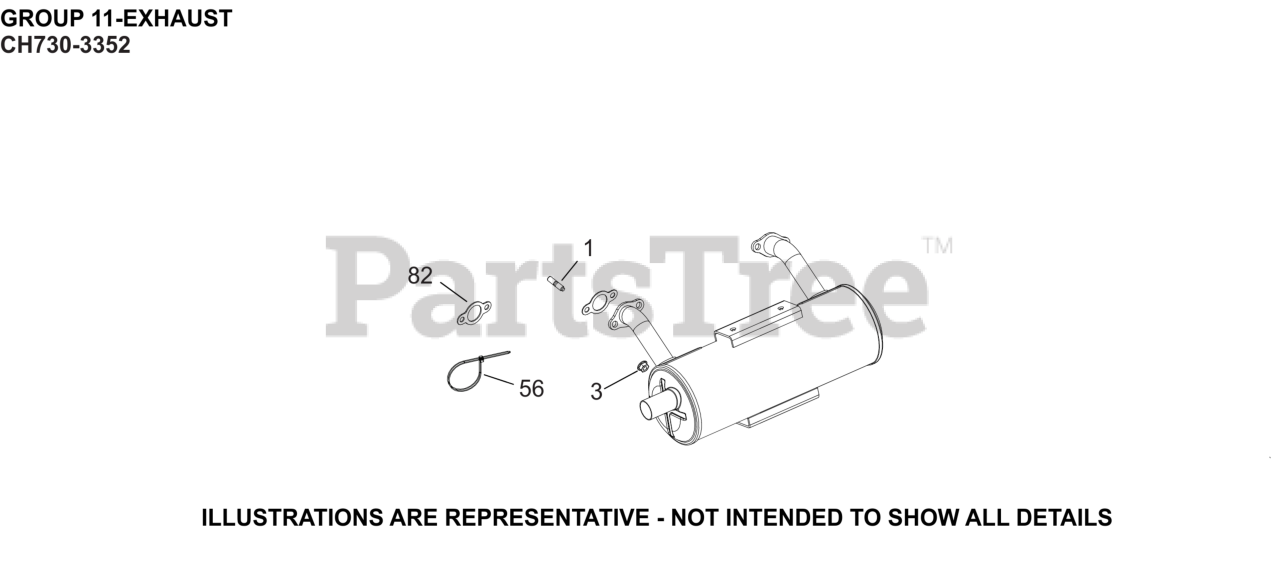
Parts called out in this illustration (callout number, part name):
1	STUD, METRIC EXHAUST
3	NUT, FLG M8X1.25
82	GASKET, EXHAUST MANIFOLD
